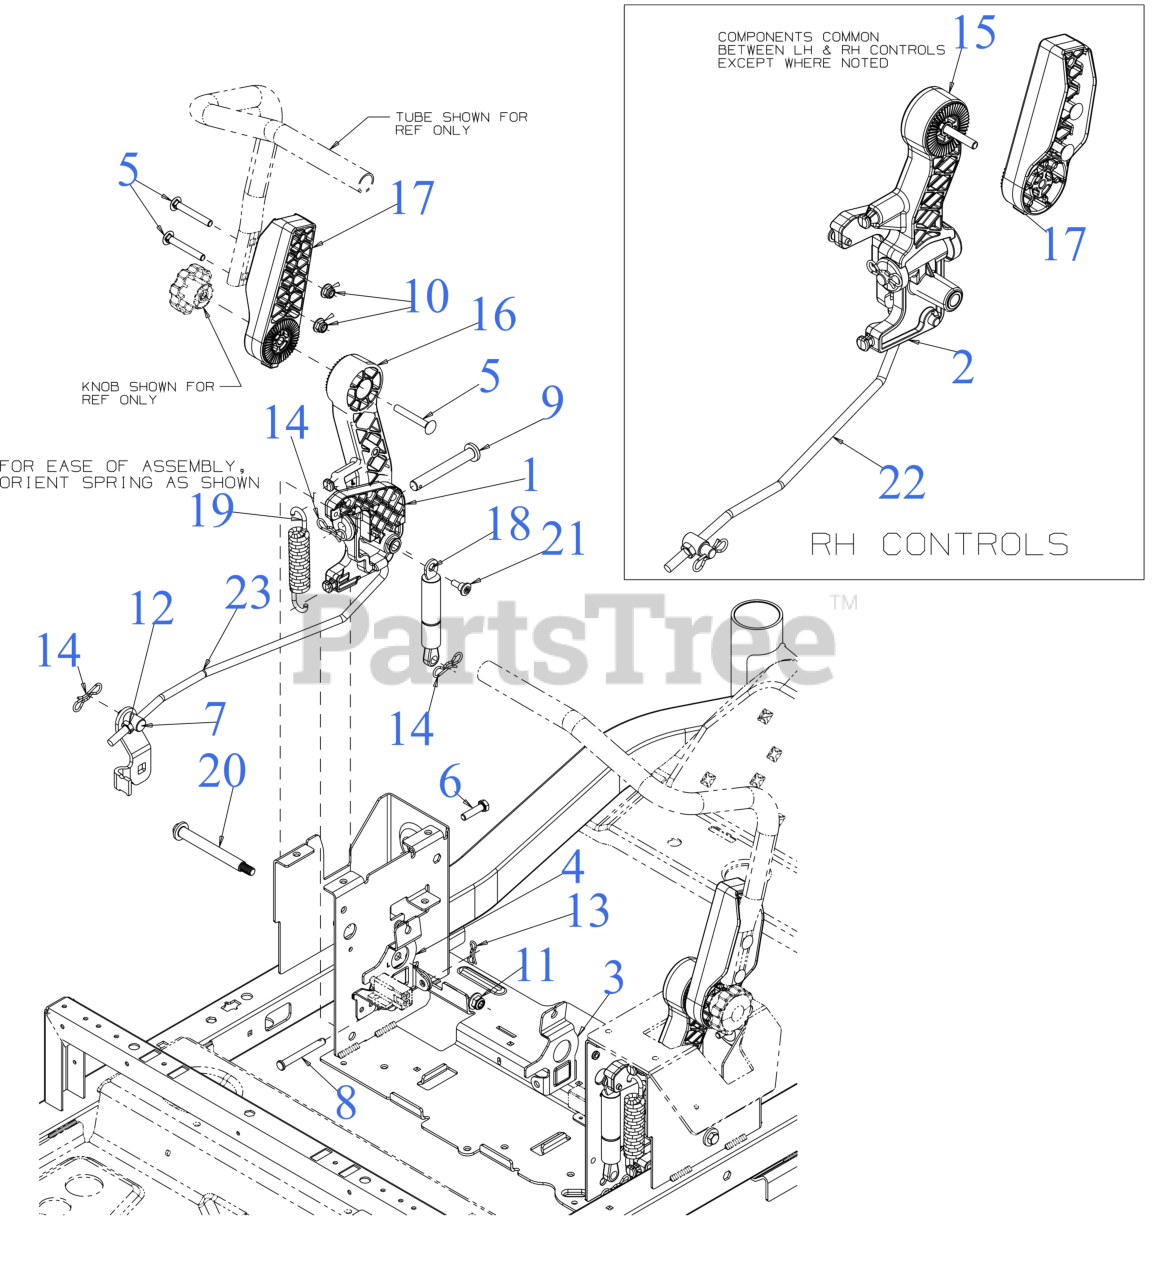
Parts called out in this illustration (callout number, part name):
1	CONTROL ACTUATOR (LH)
1	FLANGE BUSHING
2	CONTROL ACTUATOR (RH)
2	FLANGE BUSHING
3	BRAKE CABLE LEVER (RH)
4	BRAKE CABLE LEVER (LH)
5	BOLT 5/16-18 x 2.50 GR1
6	SCREW 5/16-18 x 1.25 GR5
7	CONTROL ROD FERRULE
8	CLEVIS PIN 5/16 DIA
9	CLEVIS PIN
10	FLANGE LOCK NUT 5/16-18
12	HEX JAM NUT 3/8X24
13	BOW TIE COTTER PIN 1/4-5/16
14	BOW TIE COTTER PIN
15	LAPBAR ACTUATOR (RH)
16	LAPBAR ACTUATOR (LH)
17	UPPER ADJUSTMENT HANDLE
18	DAMPNER CYLINDER
19	EXTENSION SPRING .57 x 5.38
20	SHOULDER SCREW .491x3.937 3/8-16
21	SHOULDER SCREW .394X.280:1/4-14
22	HYDRO CONTROL ROD (RH)
23	HYDRO CONTROL ROD (LH)
